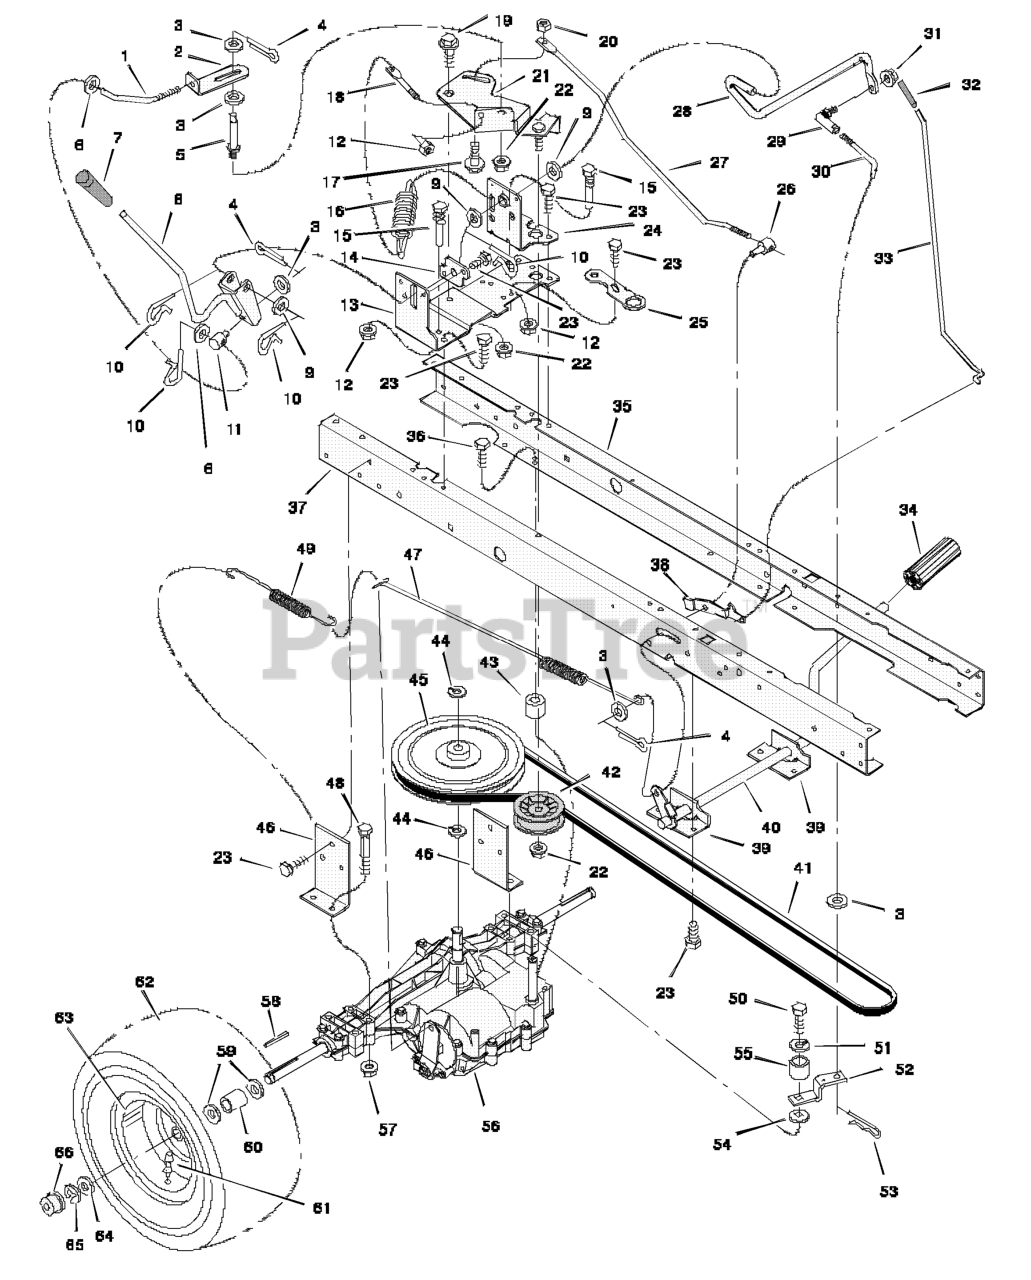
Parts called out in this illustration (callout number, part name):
1	Rod, Adjuster
2	Link, Clutch
3	Washer
4	Pin, Cotter
5	Spacer, Stud
6	Washer
8	Lever, Shift
9	Washer
10	Pin, Hair
12	Nut, Flange
13	Bracket, Shifter
14	Plate, Pivot
15	Guide, Belt
16	Spring, Extension
17	Bolt, Shoulder
18	Stud, Spring
19	Bolt, Shoulder
20	Locknut
21	Arm Assembly, Idler
22	Locknut
24	Bracket, Shift
25	Plate, Shift
26	Nut, Adjuster
27	Rod, Clutch
28	Rod, Shift
29	Joint, Ball
30	Link, Shift
31	Locknut
33	Rod, Parking Brake
34	Pedal
35	Frame, Left
37	Frame, Right
38	Latch, Parking Brake
39	Bracket, Pedal
40	Lever, Clutch/Brake
42	Pulley, Idler
44	Ring, Snap
45	Pulley, Drive
46	Bracket, Transaxle
47	Spring, Extension
48	Bolt
49	Spring, Extension
51	Lockwasher
52	Yoke, Shift
53	Pin, Hair
55	Spacer
56	Transaxle **
57	Nut, Flange
58	Key, Square
61	Stem, Valve
62	Tire *
63	Wheel & Tire Assembly
65	E- Ring
66	Cap, Hub
